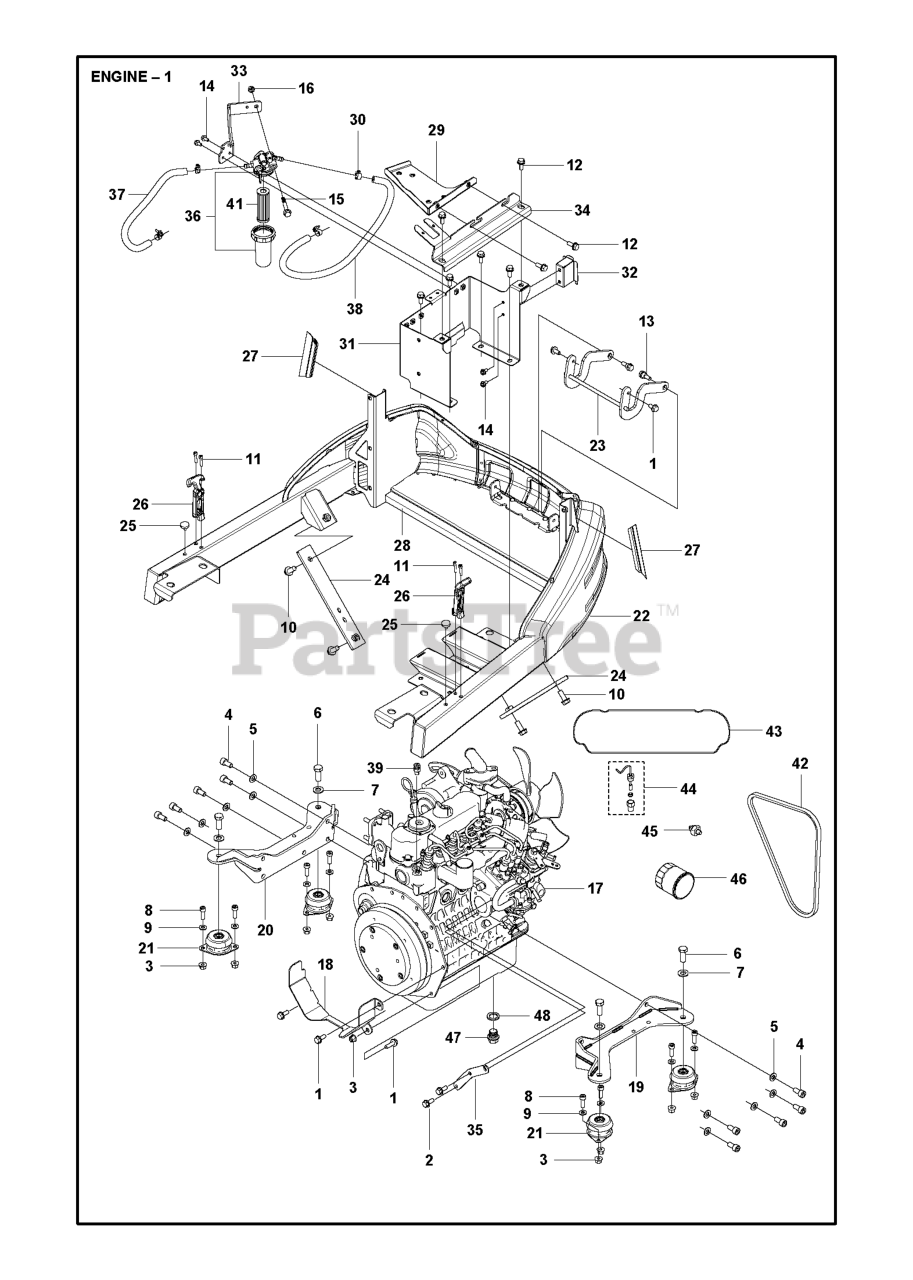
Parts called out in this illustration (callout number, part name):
3	NUT FLANGE
5	WASHER
6	Hex Head Capscrew, M12 X 1.75 X 30 DIN933ZP
7	WASHER - M12
9	WASHER BRB 8.4X17
11	SCREW IHSCM
14	SCREW EHHFM
16	LOCKNUT M8
30	RP HOSE CLAMP FUEL HOSE
